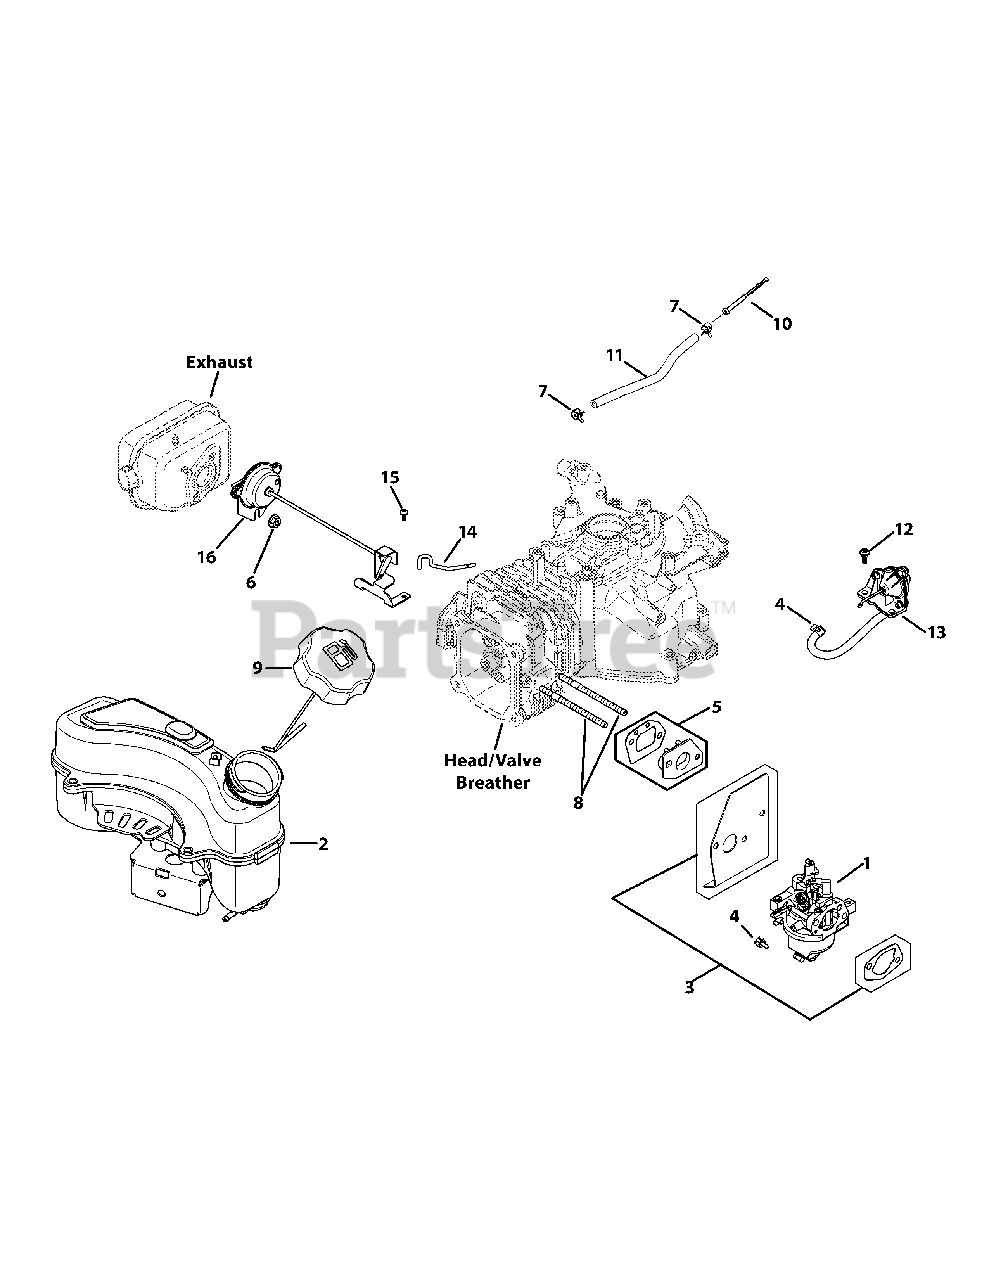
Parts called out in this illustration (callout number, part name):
1	Carburetor Kit
2	Fuel Tank Assembly Fuel (Xenoy)
3	Gasket Kit
6	Hex Flange Nut, M6
7	Hose Clamp (Non-California)
8	Carburetor Stud
9	Fuel Cap Assembly (Evap.)
10	In-Nipple Fuel Filter
11	Low-Permeation Fuel Hose (Cky.)
12	Shoulder Screw
13	Diaphragm Assembly
14	Auto Choke Linkage
15	Thread Forming Screw, M4
16	Auto Choke Arm Assembly
